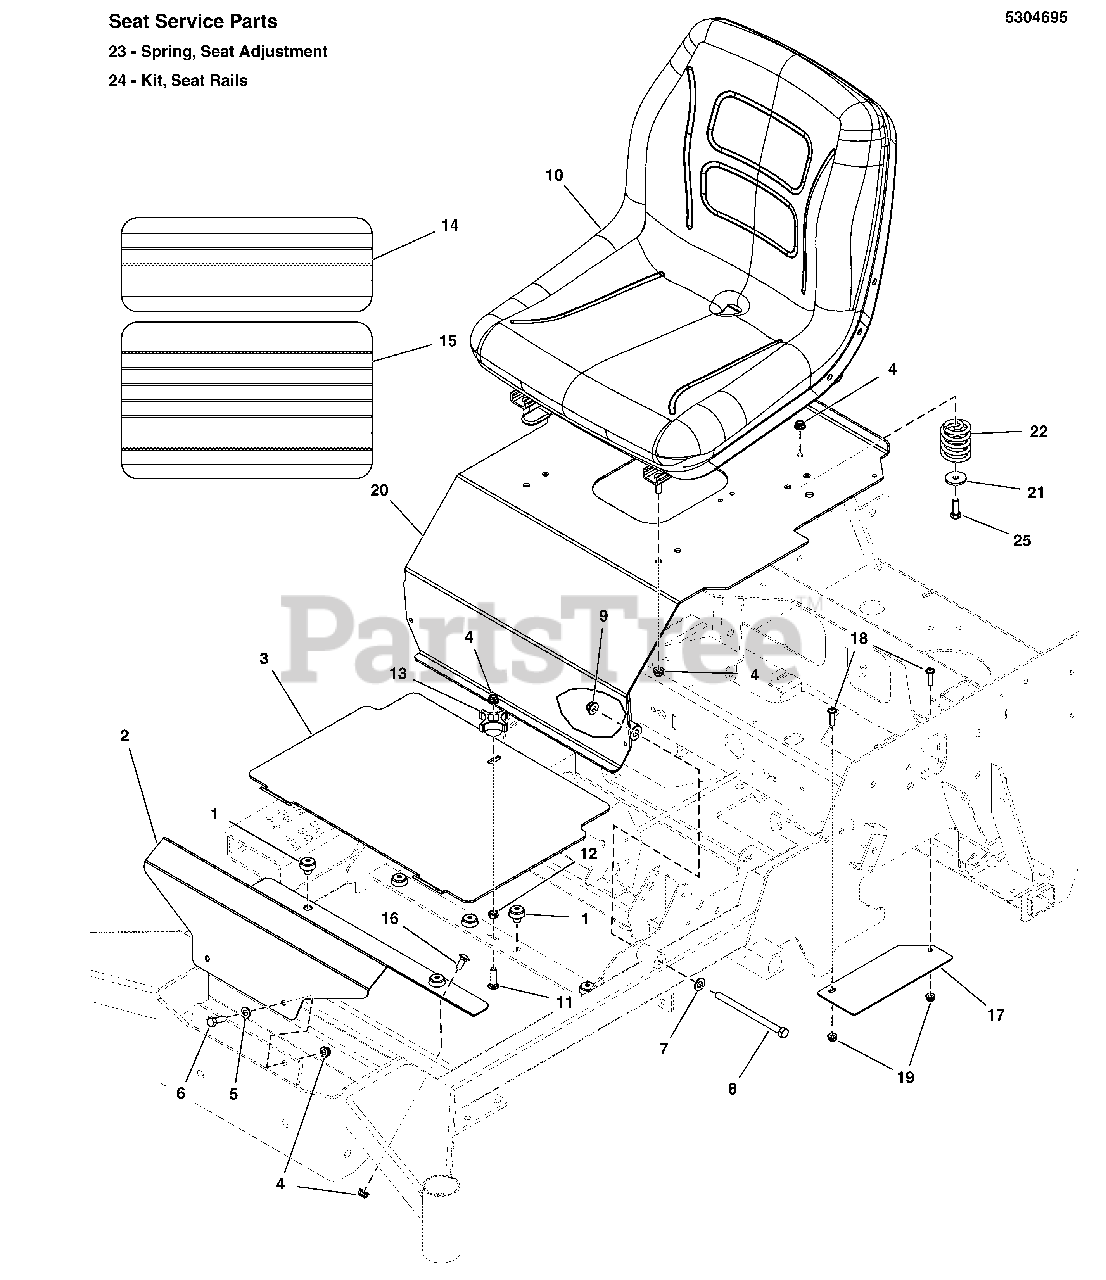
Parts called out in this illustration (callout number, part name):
1	MOUNT, Vibration
2	PLATE, FLOOR RIGID, S125XT - RED
3	PLATE, FLOOR, REMOVABLE, S125XT - RED
4	NUT, Flange Nylock, 5/16-18
5	WASHER, Flat, 5/16
6	CAPSCREW, Hex Head, 5/16-18 x 1 1/4
7	WASHER, .406
8	BOLT, 3/8-16 X 5-1/2 GD5 CZ
9	NUT, Hex Flange, Nylock, 3/8-16
10	SEAT, NO ARM REST
11	BOLT, 5/16-18 X 1-1/4, CARRIAGE, GD5, CZ
12	NUT, Hex Center Lock, 5/16-18, GRB
13	KNOB, Internal Thread, 5/16 (Used Only on 24 in. Models)
14	SAFETY WALK
15	SAFETY WALK, FLOOR PLATE, S50X, 10X17.13
16	BOLT, 5/16-18 X 3/4, CARRIAGE, GD5, CZ
17	PLATE, SEAT BELT GUARD - S125XT - BLK
18	CAPSCREW, Button Allen Head, 1/4-20 x 3/4
19	NUT, Flange Nylock , 1/4-20
20	ASSM, SEAT PLATE W/DECAL (5416034D)
21	WASHER, CLUTCH ANCHOR, 5/16
22	SPRING, SEAT SUPPORT
23	SPRING, Extension, Seat Adjustment (BLK or SLVR) (3-1/2" Total unstretched length.)
24	KIT, SEAT RAILS (COMPLETE)(SV)
25	CAPSCREW, Hex Head, 5/16-18 x 3/4
